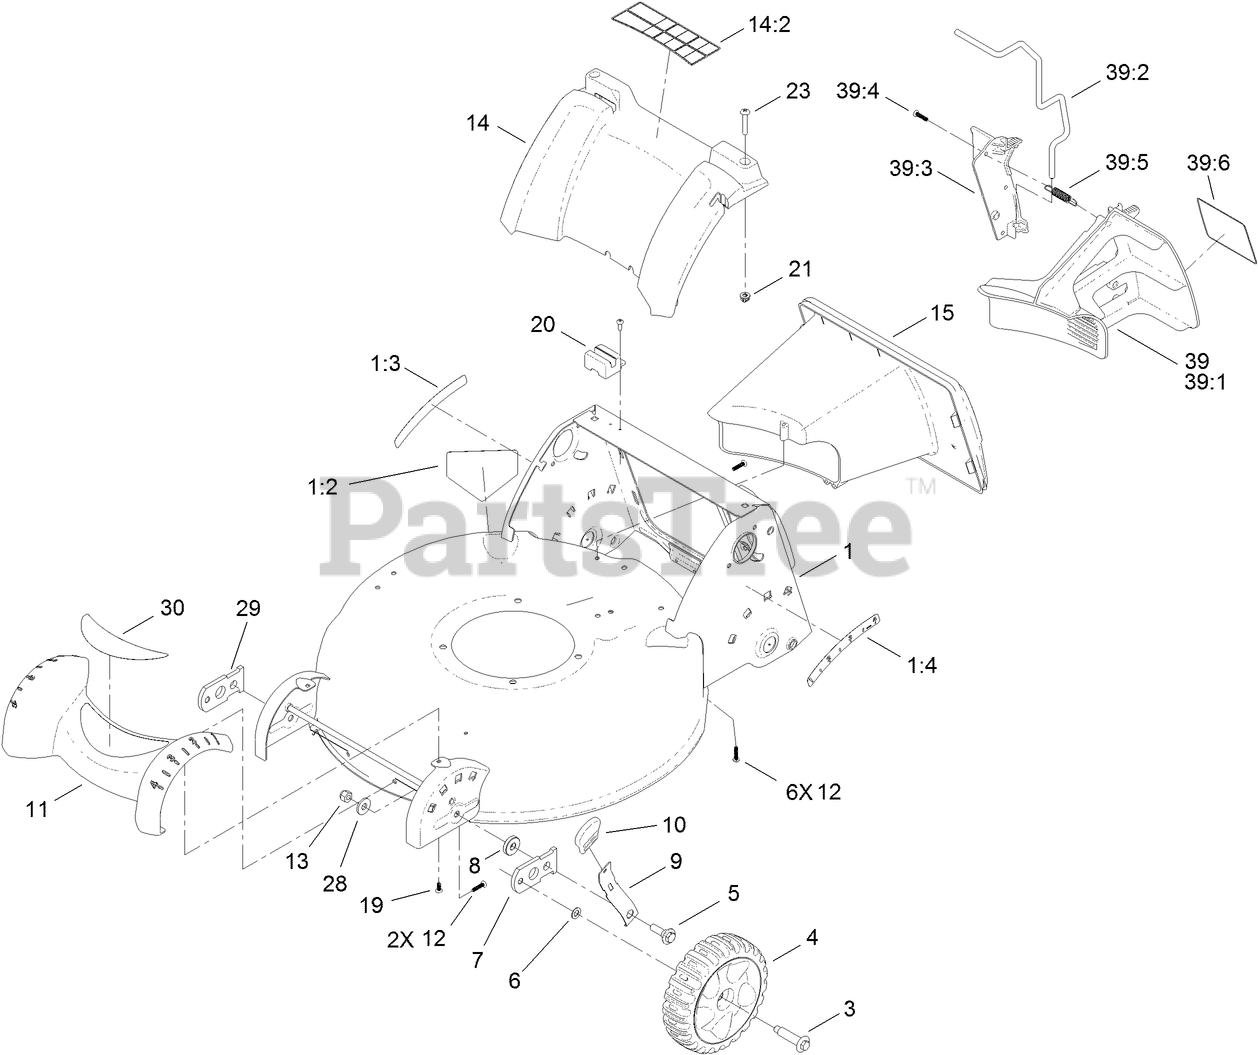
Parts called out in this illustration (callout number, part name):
1	DECK ASM
1:2	DECAL-DANGER
1:3	DECAL-HOC, RH
1:4	DECAL-HOC, LH
3	BOLT-SHOULDER
4	7 INCH WHEEL AND TIRE ASM
5	SCREW-SHOULDER, HWH
6	WASHER
7	ARM-PIVOT, RH
8	WASHER
9	ARM-SPRING
10	KNOB-HOC
11	COVER-FRONT
12	SCREW-PLASTITE
13	NUT-LOCK, NI
14	REAR COVER ASM
14:2	DECAL-WARNING
15	TUNNEL
19	SCREW-PLASTITE
20	MODULE-SWITCH
21	NUT-CLIP
23	SCREW-PTH
28	WASHER-HARDENED
29	ARM-PIVOT, LH
30	DECAL-FRONT (CE)
39	MULCH PLUG ASM
39:1	PLUG-MULCH, LH
39:2	LATCH-PLUG, MULCH
39:3	PLUG-MULCH, RH
39:4	SCREW-PLASTITE
39:5	SPRING-EXTENSION
39:6	DECAL-PLUG, MULCH
